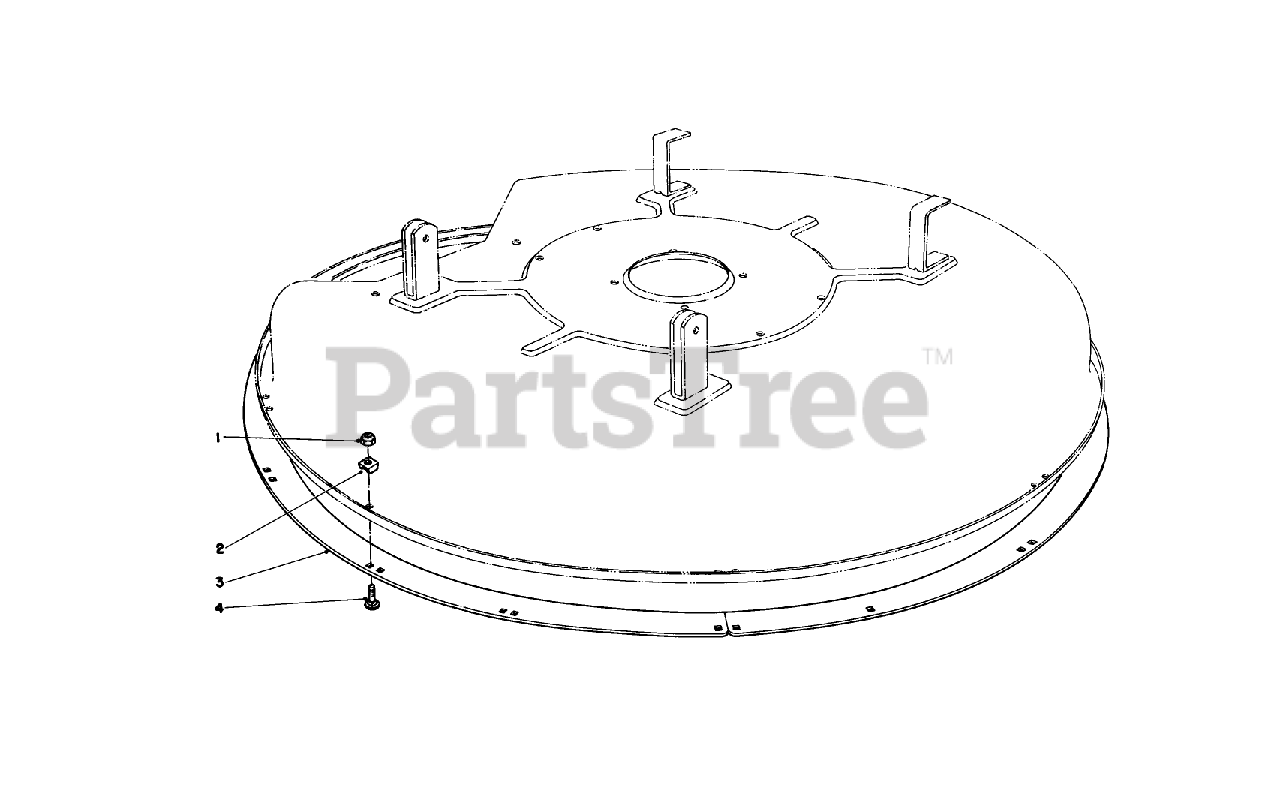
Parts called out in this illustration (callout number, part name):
1	NUT-LOCK, NI
3	DECK RING *B
4	BOLT-CARR
